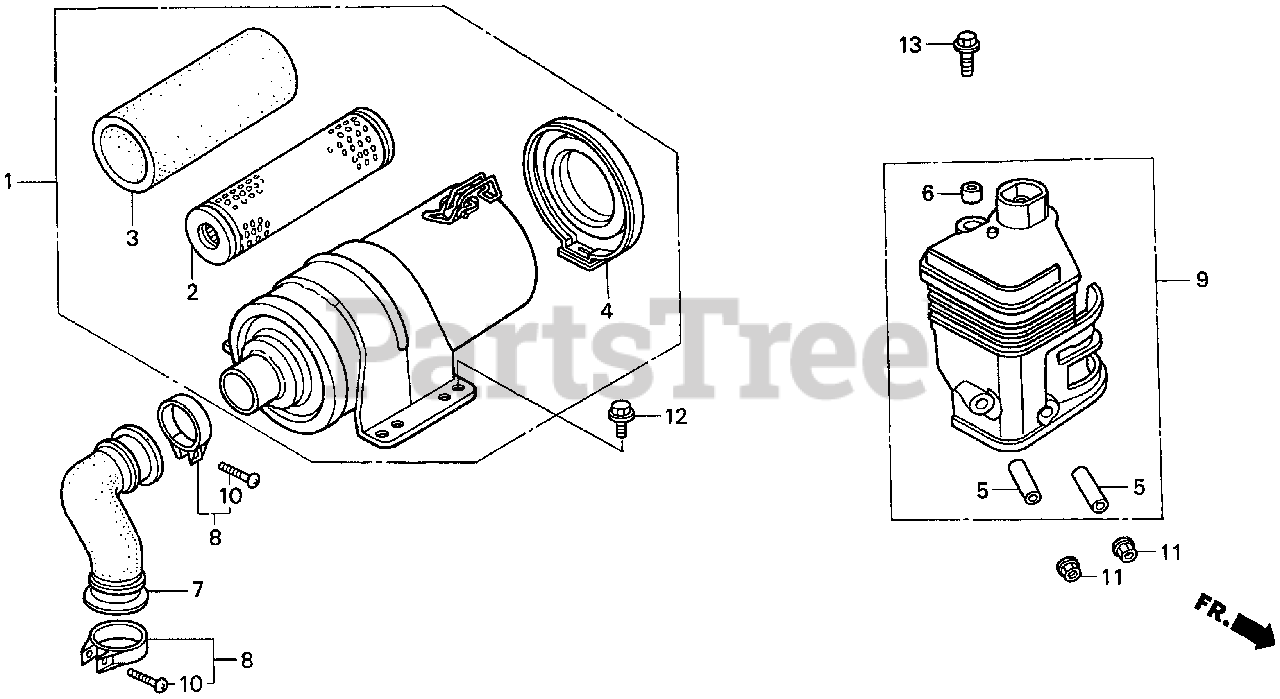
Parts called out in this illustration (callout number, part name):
1	AIR CLEANER ASSY.
2	ELEMENT, AIR CLEANER
3	FILTER (OUTER)
4	COVER, AIR CLEANER
5	COLLAR, AIR CLEANER
6	COLLAR B, AIR CLEANER
7	TUBE, AIR CLEANER CONNECTING
8	BAND, AIR CLEANER CONNECTING TUBE
9	ELBOW, AIR CLEANER
10	SCREW, PAN (4X20)
11	NUT, FLANGE (6MM)
12	BOLT, FLANGE (6X16)
13	BOLT, FLANGE (6X20)
